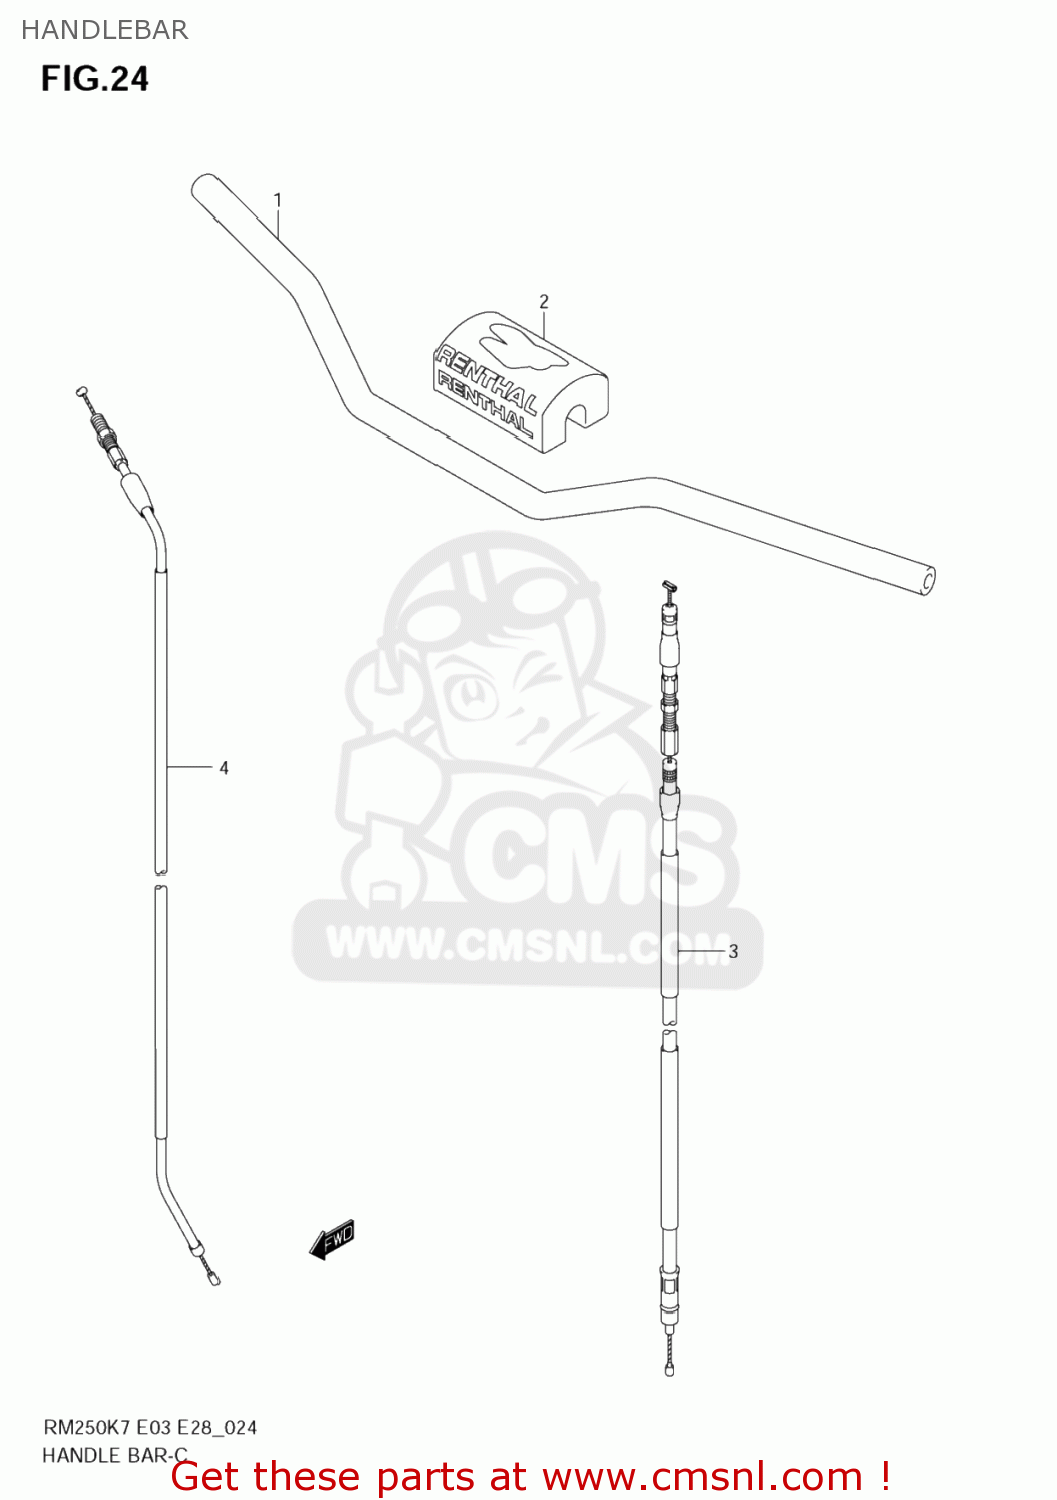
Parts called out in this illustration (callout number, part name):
1	HANDLEBAR
2	PAD SET,HANDLEBAR (NAS)
3	CABLE ASSY,CLUTCH
4	CABLE ASSY,THROTTLE
